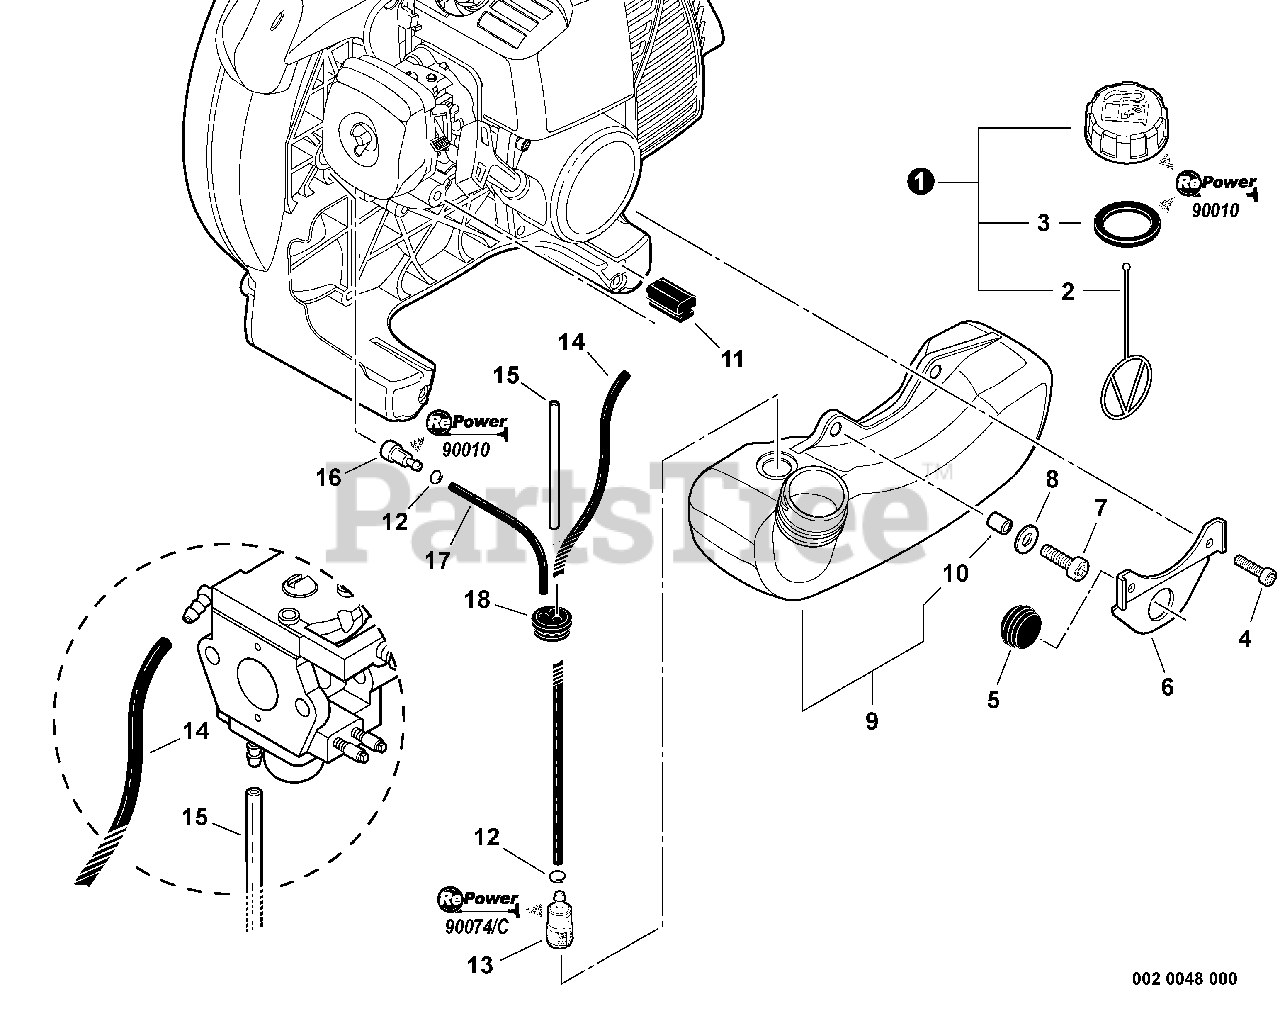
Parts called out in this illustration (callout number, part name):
1	CAP ASSY - ORANGE
2	CONNECTOR, CAP
3	GASKET, CAP
4	SCREW - 4X16
5	CUSHION
6	BRACKET, FUEL TANK
7	SCREW - 5X16
8	WASHER - 5
9	FUEL TANK ASSY
12	CLIP - 6
13	FILTER, FUEL
14	PIPE - 3X5X230 -- BLACK
15	PIPE - 3X6X85 -- CLEAR
16	VENT, FUEL TANK
17	PIPE - 3X6X80 -- BLACK
18	GROMMET
19	Repower CAP AND VENT KIT
20	RePower TUNE-UP KIT
